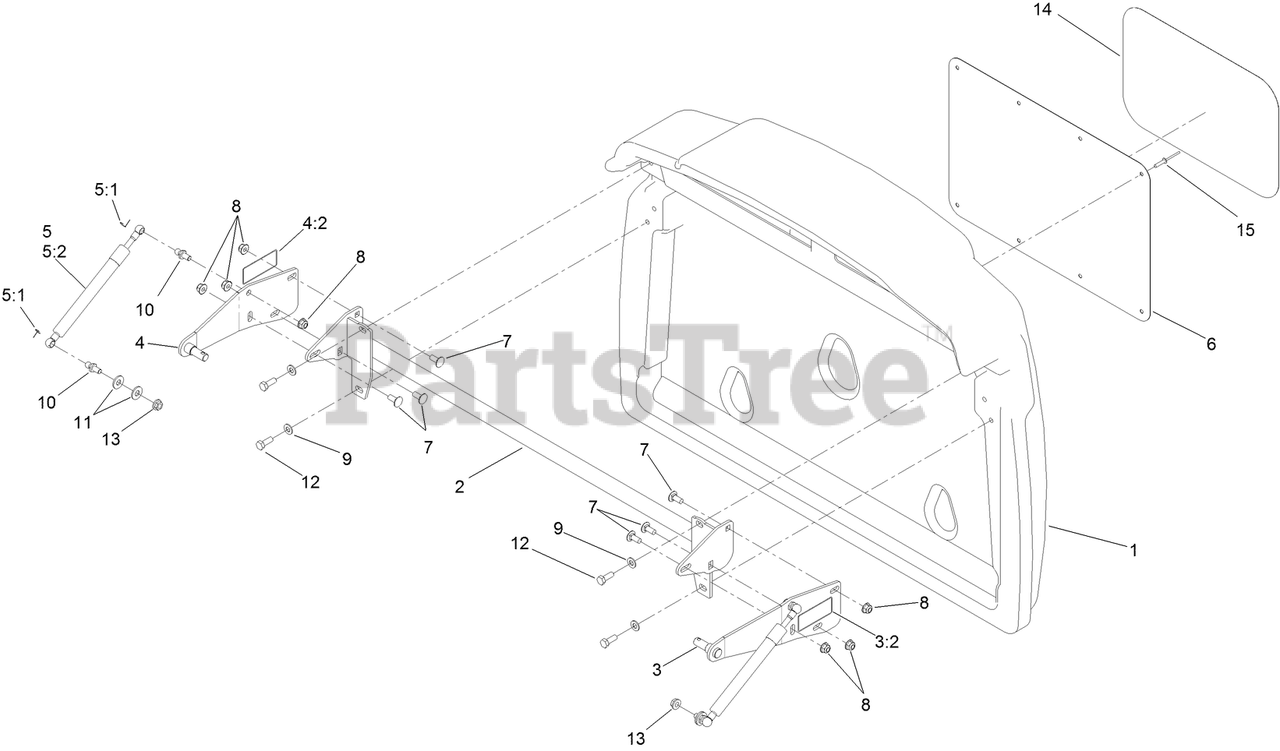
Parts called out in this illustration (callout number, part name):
1	DOOR-HOPPER
2	SUPPORT-DOOR
3	LH DOOR PIVOT ASM
3:2	DECAL-WARNING, PINCH POINT
4	RH DOOR PIVOT ASM
4:2	DECAL-WARNING, PINCH POINT
5	DAMPER KIT
5:1	CLIP-RETAINER
5:2	SHOCK-GAS TENSION
6	PLATE-DOOR, HOPPER
7	SCREW-CARR
8	NUT-HF, NI
9	WASHER-PLAIN
10	STUD-BALL
11	WASHER-FLAT
12	SCREW-HH
13	NUT-HF
15	RIVET-TRIFOLD
